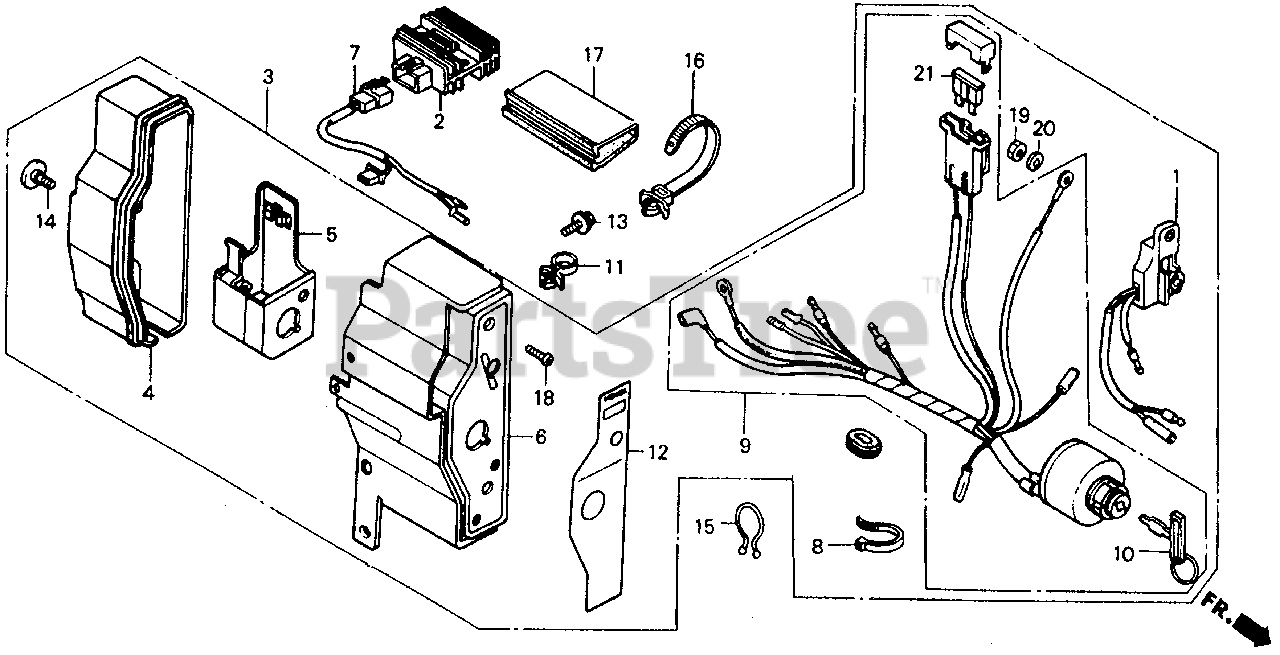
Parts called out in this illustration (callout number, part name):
1	ALERT UNIT, OIL (SEL)
2	RECTIFIER ASSY., REGULATOR
3	BOX ASSY., CONTROL (10A) *R8* (EXTERNAL-ALERT) (BRIGHT RED)
4	CASE, CONTROL
5	BRACKET, CASE MOUNTING
6	PANEL, CONTROL *R8* (BRIGHT RED)
7	SUB-WIRE HARNESS ASSY.
8	BAND
9	SWITCH ASSY., COMBINATION
10	KEY
11	HOLDER, STOP SWITCH WIRE
12	MARK, CONTROL BOX (EXTERNAL-ALERT-REG)
13	BOLT, FLANGE (6X12) (CT200)
14	SCREW, SPECIAL (6X12)
15	CLIP, PURSE LOCK
16	STRAP, CABLE (118MM) *NH1L* (BLACK)
17	TUBE, FASTENER (30)
18	SCREW, PAN (4X12)
19	NUT, HEX. (4MM)
20	WASHER, SPRING (4MM)
21	FUSE, BLADE (15A)
